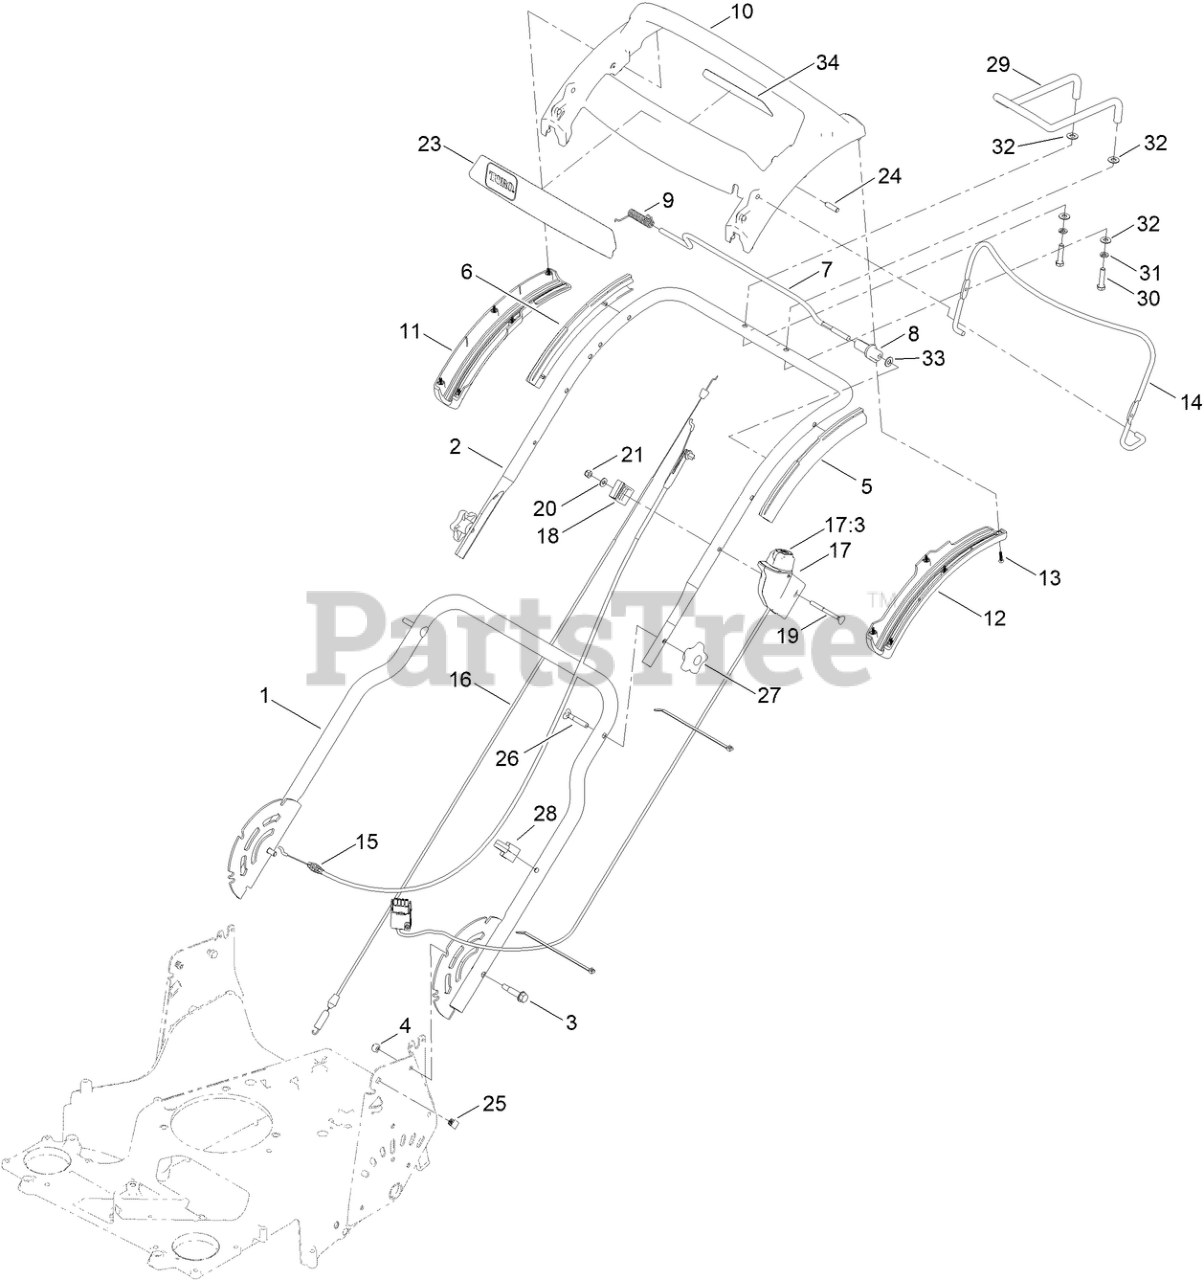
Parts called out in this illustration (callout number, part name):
1	HANDLE-LOWER, ASM
2	HANDLE-UPPER
3	BOLT-SHOULDER, HHF
4	NUT-HEX
5	GUIDE-CURVED, LH (RWD)
6	GUIDE-CURVED, RH (RWD)
7	ROD-CONTROL, TRACTION
8	LEVER-TRACTION, RWD
9	SPRING-TORSION
10	HANDLE-PERSONAL PACE, CURVED
11	BOTTOM-HANDLE, RH
12	BOTTOM-HANDLE, LH
13	SCREW-PPH
14	BAIL-BRAKE
15	CABLE-BRAKE, PP BS
16	CABLE-TRACTION
17	STARTER SWITCH ASM
17:3	STARTER BUTTON, 2-SP
18	CLAMP-CABLE
19	SCREW-HANDLE
20	WASHER-FLAT
21	NUT-HEX
23	DECAL - ADS, HANDLE
24	PIN-HANDLE, PP
25	PLUG-SQUARE
26	SCREW-HANDLE
27	KNOB-HANDLE
28	GUIDE-CABLE
29	HANDLE-ASSIST, STEEL
30	SCREW-HH
31	WASHER-LOCK
32	WASHER
33	WASHER-PLAIN
34	DECAL-CONTROLS (60V, START)
